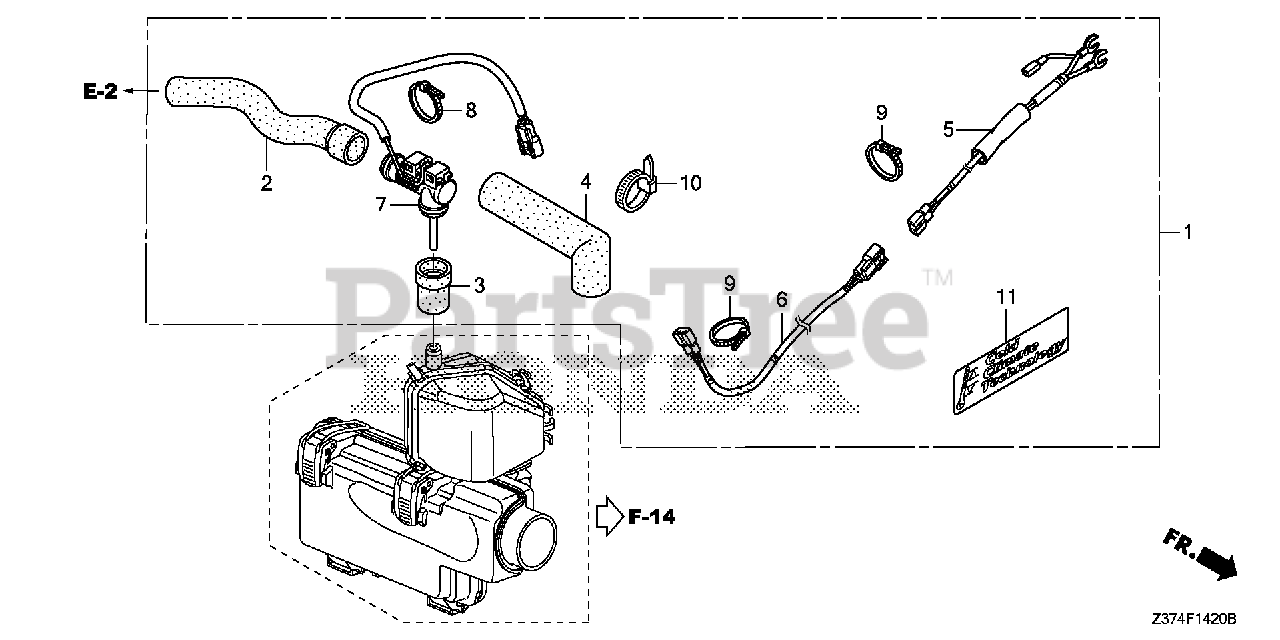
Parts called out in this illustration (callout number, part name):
1	HEATER KIT, BREATHER
2	TUBE A, BREATHER
3	TUBE B, BREATHER
4	INSULATOR, BREATHER TUBE
5	SUB-WIRE ASSY.
6	WIRE ASSY., EXTENSION
7	HEATER ASSY., BREATHER
8	BAND A, HARNESS (NATURAL)
9	BAND A, HARNESS (NATURAL)
10	BAND, WIRE (165MM) (BLACK)
11	MARK (CCT)
